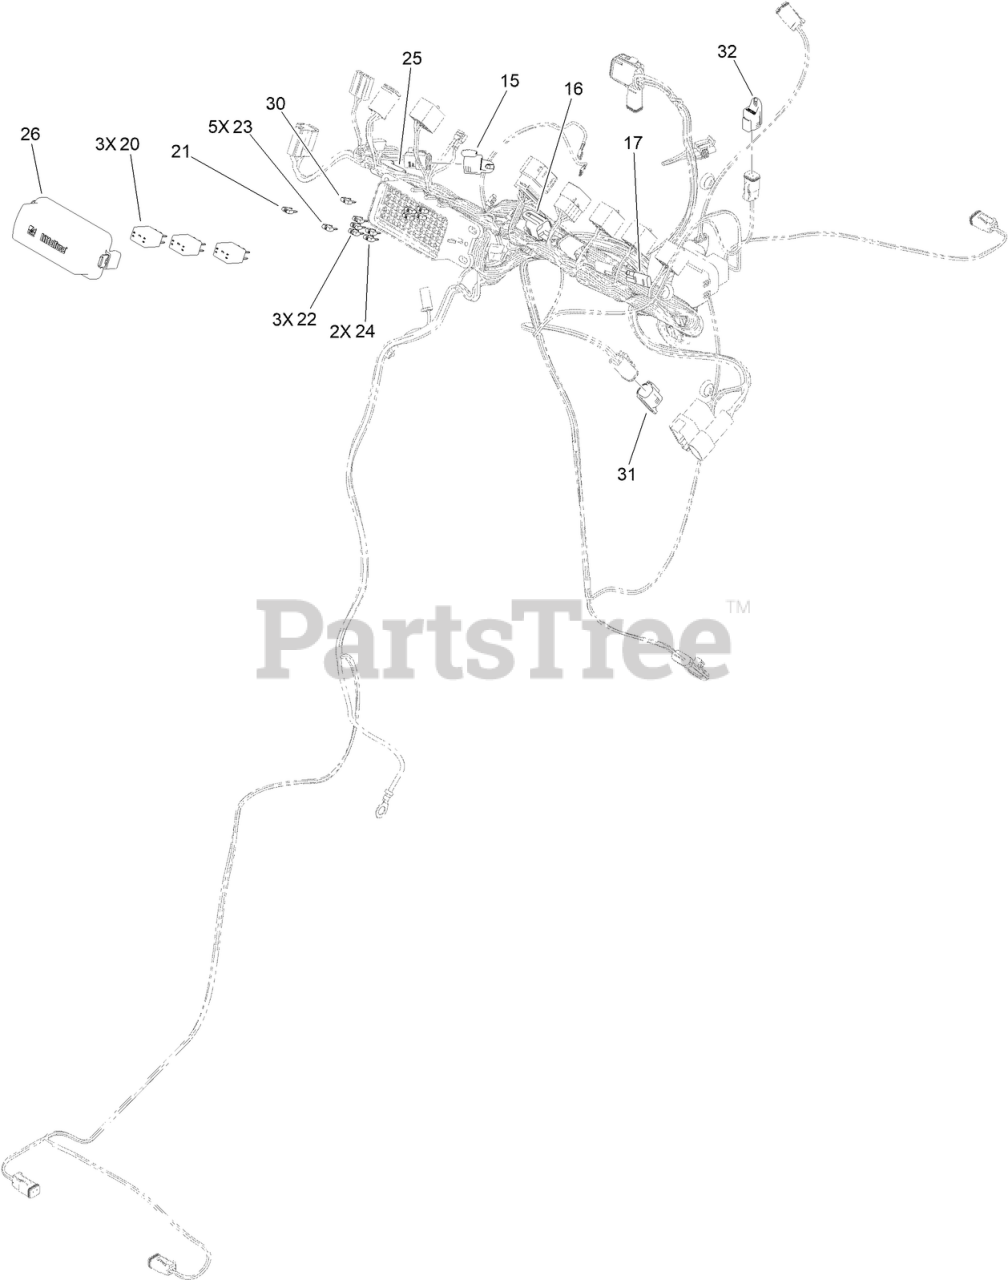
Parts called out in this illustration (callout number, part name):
15	CAP-PLUG, 3 WAY
16	CAP-PLUG, 6 WAY
17	CAP-PLUG
20	RELAY-280 ISO
21	FUSE-MINI BLADE, 20 AMP
22	FUSE-MINI BLADE, 7.5 AMP
23	FUSE-MINI BLADE, 10 AMP
24	FUSE-MINI BLADE, 15 AMP
25	RESISTOR-120 OHM
26	COVER-LITTELFUSE, PDM 60F
30	FUSE-MINI BLADE, 5 AMP
31	CAP-DEUTSCH, DUST, 4 WAY
32	CAP-DUST, 2 WAY
